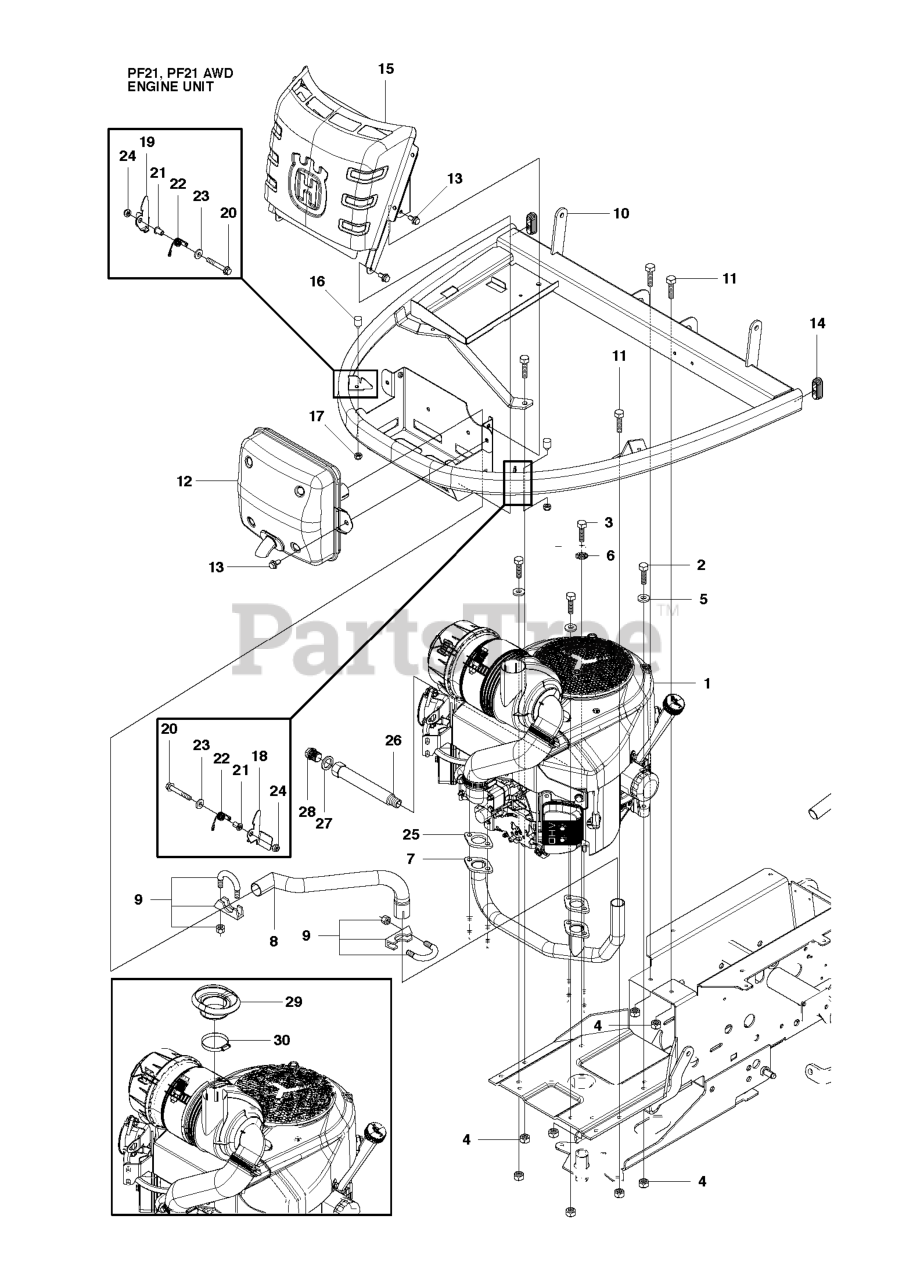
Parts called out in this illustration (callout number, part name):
4	LOCKNUT M8
5	WASHER BRB 8.4X17
9	CLAMP
13	SCREW EHHFM
17	LOCKNUT M5
23	WASHER - 26X6.5X1.6
24	LOCKNUT M6
